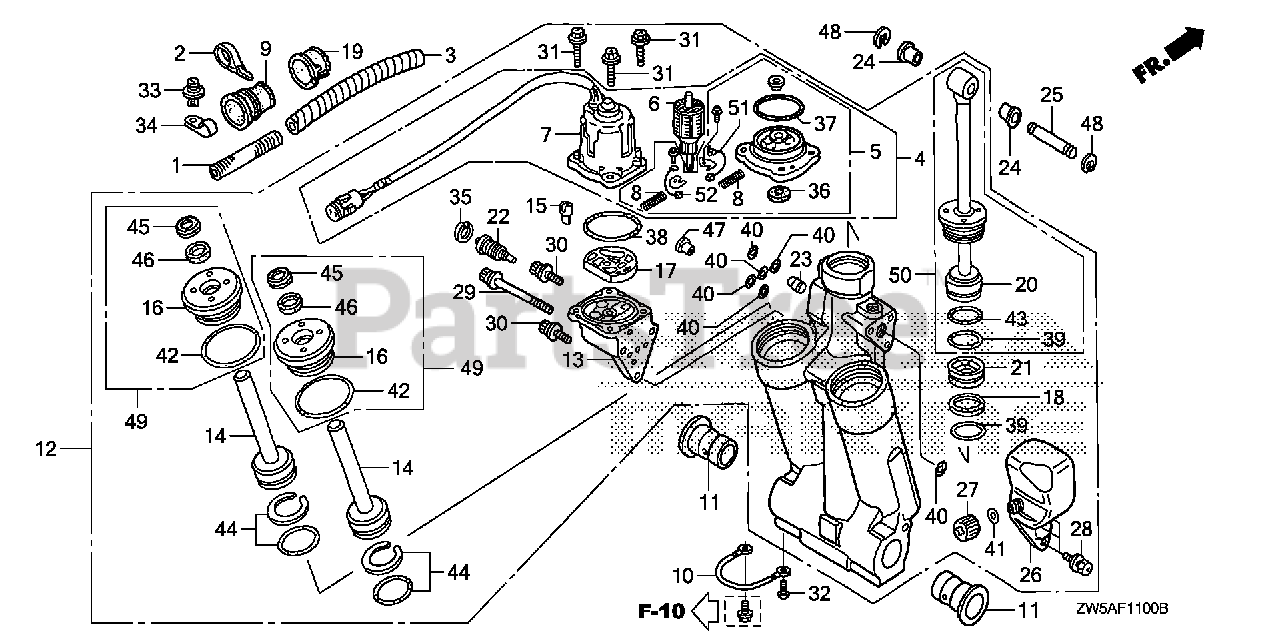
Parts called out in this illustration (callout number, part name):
1	TUBE, CORRUGATE (10MM)
2	BAND (BLACK 3.5X140)
3	TUBE, SPIRAL (12X14.6)
4	MOTOR ASSY., POWER TILT
5	BRACKET ASSY.
7	YOKE ASSY.
8	SPRING, MOTOR
9	GROMMET, CASE (LOWER) (C)
10	WIRE, LEAD (1.5X116MM)
11	BUSH, SWIVEL CASE
12	TRIM-TILT ASSY., POWER
13	PUMP ASSY.
14	ROD, PISTON (B)
15	JOINT, DRIVE
16	GUIDE, ROD
18	RING, BACK-UP
19	BUSH, MOTOR CODE
20	ROD, PISTON
21	PISTON, FREE
22	VALVE, MANUAL
23	VALVE, RESERVOIR
24	BUSH, CYLINDER (LOWER)
25	PIN, CYLINDER (UPPER)
26	TANK, OIL
27	CAP, OIL TANK
28	BOLT, RECESSED
29	BOLT A, SOCKET
30	BOLT B, SOCKET
31	BOLT, HEX.
32	SCREW, PAN (6X8)
33	SCREW, RIVET (5X10)
34	CLIP (10.7MM)
35	CIRCLIP (INNER)
37	O-RING (2.0X70.5)
38	O-RING (1.8X69.6)
39	O-RING (3.5X38.7)
40	O-RING (1.8X7.7)
41	O-RING (1.9X11)
42	O-RING (3.5X35.7)
43	O-RING (3.5X41.7)
44	O-RING SET (3.5X31.7)
45	SEAL, WATER
47	COLLAR, ORIFICE
48	E-RING (15MM)
49	GUIDE, ROD
50	ROD, PISTON
51	BREAKER ASSY.
52	BRUSH ASSY.
